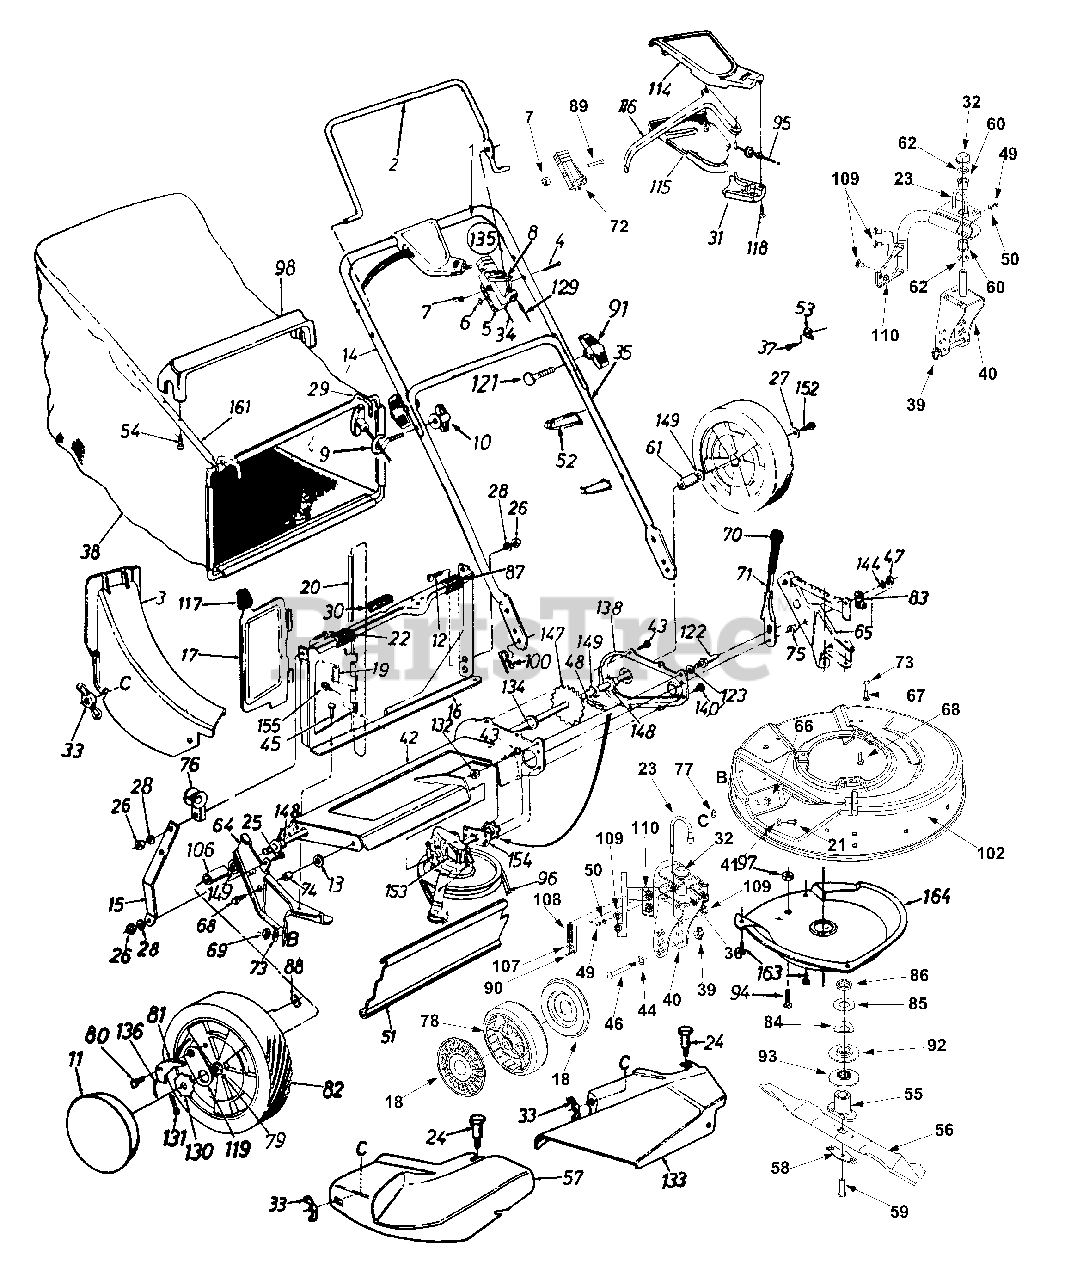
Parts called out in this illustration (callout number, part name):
1	Foam Handle
3	Rear Discharge Chute Ass'y
4	Oval C-Sunk Screw
5	Throttle Body
6	Spring Washer .66"
7	Hex L-Nut 1/4-20
8	Throttle Lever
9	Rope Guide
10	Wing Nut 1/4-20
11	Hub Cap Spoke
12	Truss Machine Screw 1/4-14 x .625
13	Flat Washer .383" ID x 1" OD
19	Torsion Spring
20	Pivot Pin
21	Carriage Bolt 1/4-20 x .62"
22	Truss Machine Screw 1/4-20 x .75"
23	Lock Pin
24	Shoulder Bolt .312 x .18
25	Hex Bolt 1/4-20 x .62"
26	Hex Nut 1/4-20
27	Bell Washer 1/4"
28	Lock Washer 1/4"
30	Foam Strip
31	SP Control Cover
32	Push Cap
33	Wing Nut w/ Washer
34	Throttle Control Wire 61"
37	Hex Tap Screw #10-32 x .62"
38	Grass Bag
39	Wing Nut
41	Flat Washer .344" ID x .62"
44	Wave Washer
45	Hex Tap Screw 1/4 x .62"
46	Caster Axle
47	Hex Lock Nut 3/8-24
48	#48 Chain .500" Pitch x 30 Links
49	Lube Fitting
50	Flat Washer
51	Rear Flap
52	Cable Tie
53	Cable Clamp
54	Hex Screw #12 x 1.25"
55	Blade Adapter Kit
56	21" Standard Blade
56	21" Mulching Blade
57	Mulching Plug
58	Blade Bell Support
59	Hex Bolt 3/8-24 x 1.5"
60	Flange Bearing
61	Spacer .513" ID x .69"
62	Flat Washer 5/8 ID x 1.0 OD
67	Hex Tap Screw 5/16-18
68	Hex Tap Screw 3/8-16
69	Hex Nut 5/16-18
71	Height Adjuster Lever
72	Throttle Housing w/o Lever
73	Bell Washer 5/16"
74	Spacer
75	Shoulder Spacer .50"
76	Rope Guide
77	Bolt Retainer
78	Front Wheel Ass'y Comp
79	Bearing 1/2" ID
80	Shoulder Screw
81	Pawl
82	Rear Wheel Ass'y Comp
83	Clamp
84	Flat Washer
85	Spring Washer .89" ID
86	Crankshaft Spacer
87	Panel Clip
88	Weld L-Nut 1/4-20
89	Screw 1/4-20 x 20
90	Cotter Pin
91	Hand Knob
92	Pulley Half-Upper
93	Pulley Half-Lower
94	Machine Screw 1/4-20
95	Drive Cable Models
96	V-Belt Models
97	Sems Nut 1/4-20
98	Bag Handle
100	Hairpin Clip
107	Flat Washer .330 ID x .630 OD
108	Compression Spring
109	Carriage Bolt 5/16-18 x .62
110	Flange Lock Nut 5/16-18
114	SP Control Cover
115	SP Control Cover
116	Control Lever
117	Door Grip
118	C Sunk Tap Screw #10-16 x .625
119	Pawl Plate
121	Curved Carriage Bolt 5/16-18 x 2"
122	Shoulder Pin 3/8-24 x 1.43"
123	Lock Washer 3/8" ID
129	Control Cable
130	Ratchet Wheel 1.62" OD
131	Cotter Pin
132	Hex Jam Nut 3/8-24
133	Side Chute Deflector Ass'y
134	Hex Flange Bearing
135	Throttle Box Comp
136	Nylon Spring
144	Flat Washer
147	Rear Shaft Ass'y
148	Hex Flange Bearing .506" ID
149	Flat Washer .531" x .930"
152	Hex Bolt 1/4-20 x .62
153	Transmission Comp
155	Hex Tap Screw #10 x .38
163	Hex Tap Screw 1/4 x .38"
